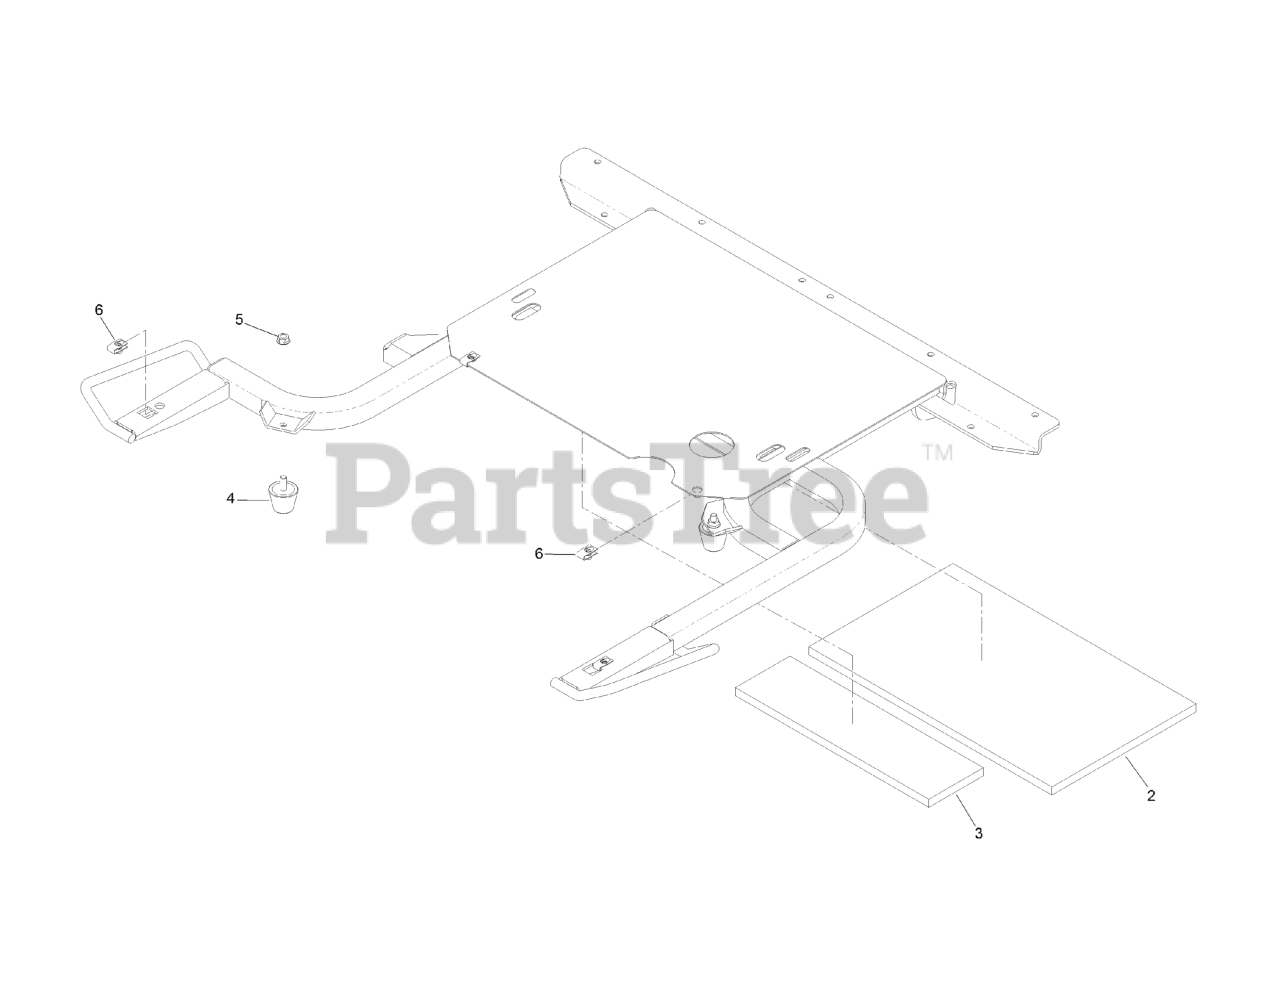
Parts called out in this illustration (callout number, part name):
2	INSULATION-FOAM PAD, REAR
3	INSULATION-FOAM PAD, FRON
4	BUMPER-RUBBER
